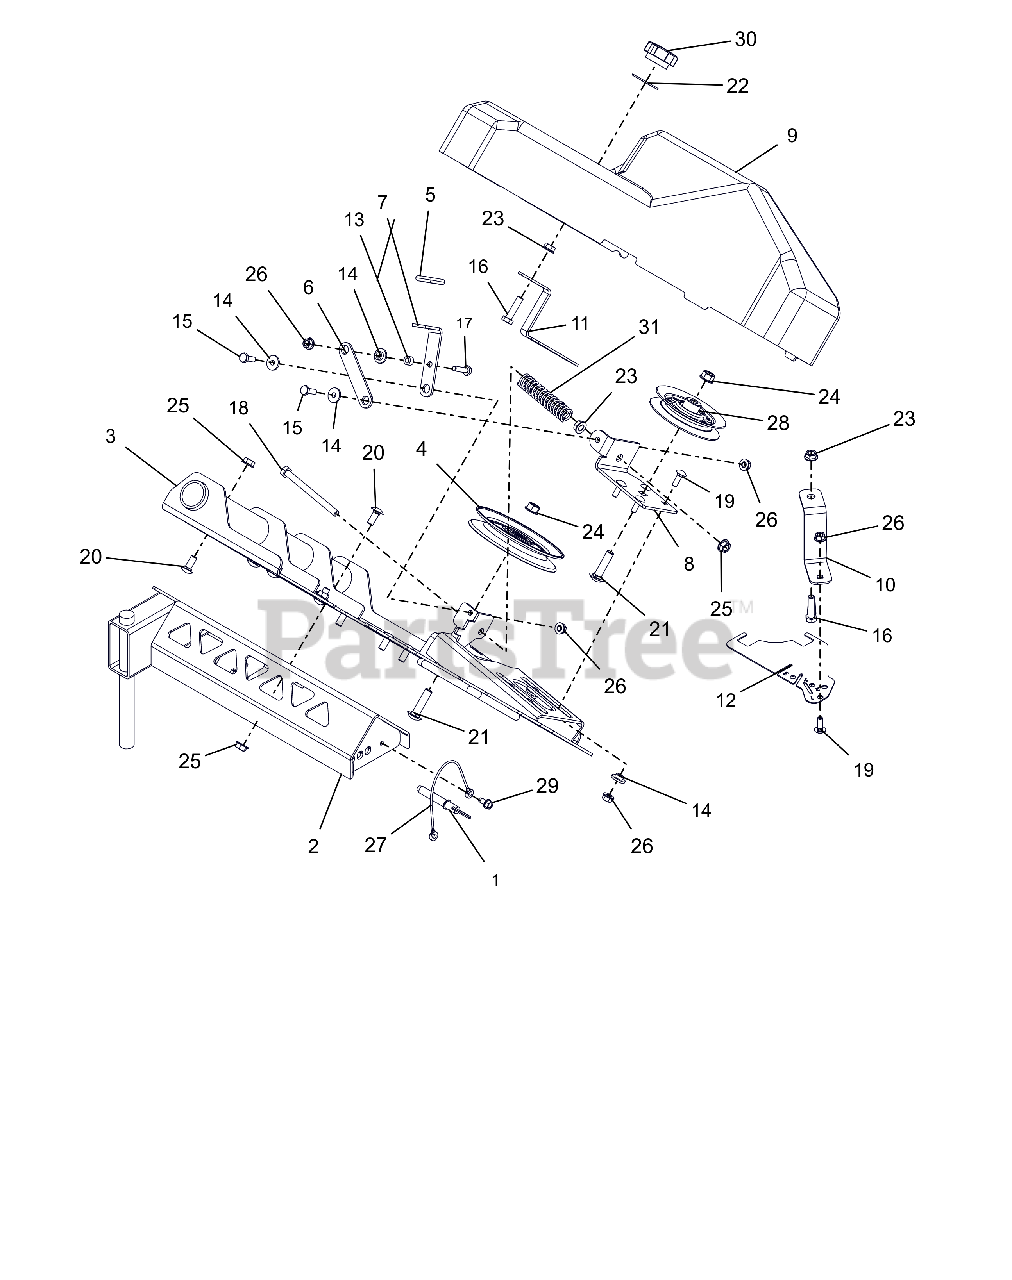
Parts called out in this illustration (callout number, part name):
1	PIN, SPRING BALL .375OD X 1.50
2	WLDMT, BLOWER MOUNT
3	WLDMT, BLOWER SPINDLE MOUNT
4	IDLER, V-5.00
5	GRIP, SEAT LEVER, GREY
6	LINK, TENSIONER
7	HANDLE, TENSIONER
8	PLATE, TENSION PULLEY MOUNTING
9	COVER, BELT HD BLOWER
10	PLT, DECK COVER MNT
11	PLT, COVER MNT
12	PLT, TEMPLATE
13	BUSHING, .26 ID X .44 OD X .26
14	BSHG-FLG .265X.437X.250X.750
15	@BLT-HEX .25-20X.75 GR5 YWZC
16	@BLT-HEX .31-18X1.25 GR5 YWZC
17	@BLT-HEX .25-20X1.00 GR5 YWZC
18	@BLT-HEX .31-18X4.00 GR5 YWZC
19	@BLT-RDHDSQNK .25-20X.75 G5YZ
20	@BLT-RHDSSQNK .31-18X.75 G5YZ
21	@BLT-RHDSSQNK .38-16X1.50 G5YZ
22	WSHR-FL-STL .380X1.50X.062 YWZ
23	@NUT-SPNLK-FLG .312-18 YWZC
24	@NUT-LK-TOP-FLG .38-16 YWZC
25	@NUT-LK-TOP-FLG .31-18 YWZC
26	@NUT-LK-TOP-FLG .25-20 YWZC
27	CABLE, 12.0 LANYARD, NYLON
28	V-IDLER, 4.00X.38
29	SCR-TAP .25-20X.50 HWH TR YWZ
30	KNOB-CLAMPING, .312-18 NYLOC
31	SPRING, COMPRESSION
